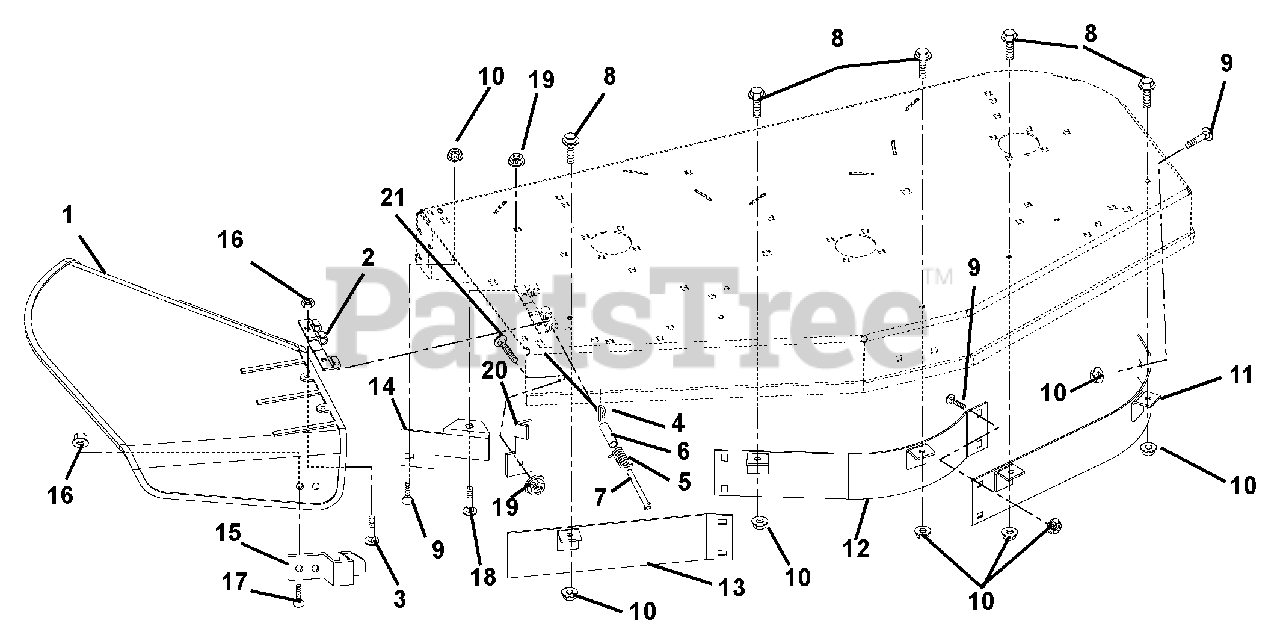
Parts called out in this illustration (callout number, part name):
1	DEFLECTOR, CHUTE
2	HINGE PLATE
3	@BLT-RDHDSQNK .25-20X.75 G5YZ
4	PIN-HAIR INT .08X.18X1.18 YWZC
5	SG-TORS .095X.50X 1.0
6	BSHG-SLV .334 X .502 X 1.437
7	PIN, 5/16 X 5.80"
8	BLT-SERHFWH .312-18X.75 YWZC
9	@BLT-RHDSSQNK .31-18X.75 G5YZ
10	@NUT-LK-NYL-FLG .31-18 YWZC
11	BAFFLE - LEFT FRONT - 40"
12	BAFFLE - CENTER FRONT - 40"
13	BAFFLE - RIGHT FRONT - 40"
14	DEFLECTOR-40"
15	FLAT SPRING
16	@NUT-LK-TOP-FLG .25-20 YWZC
17	@BLT-RDHDSQNK .25-20X.50 G5YZ
18	@BLT-RDHDSQNK .38-16X1.00 G5YZ
19	@NUT-LK-NYL-FLG .38-16 YWZC
20	BRACKET, CHUTE LOCK
21	@BLT-RDHDSQNK .38-16X1.50 G5YZ
